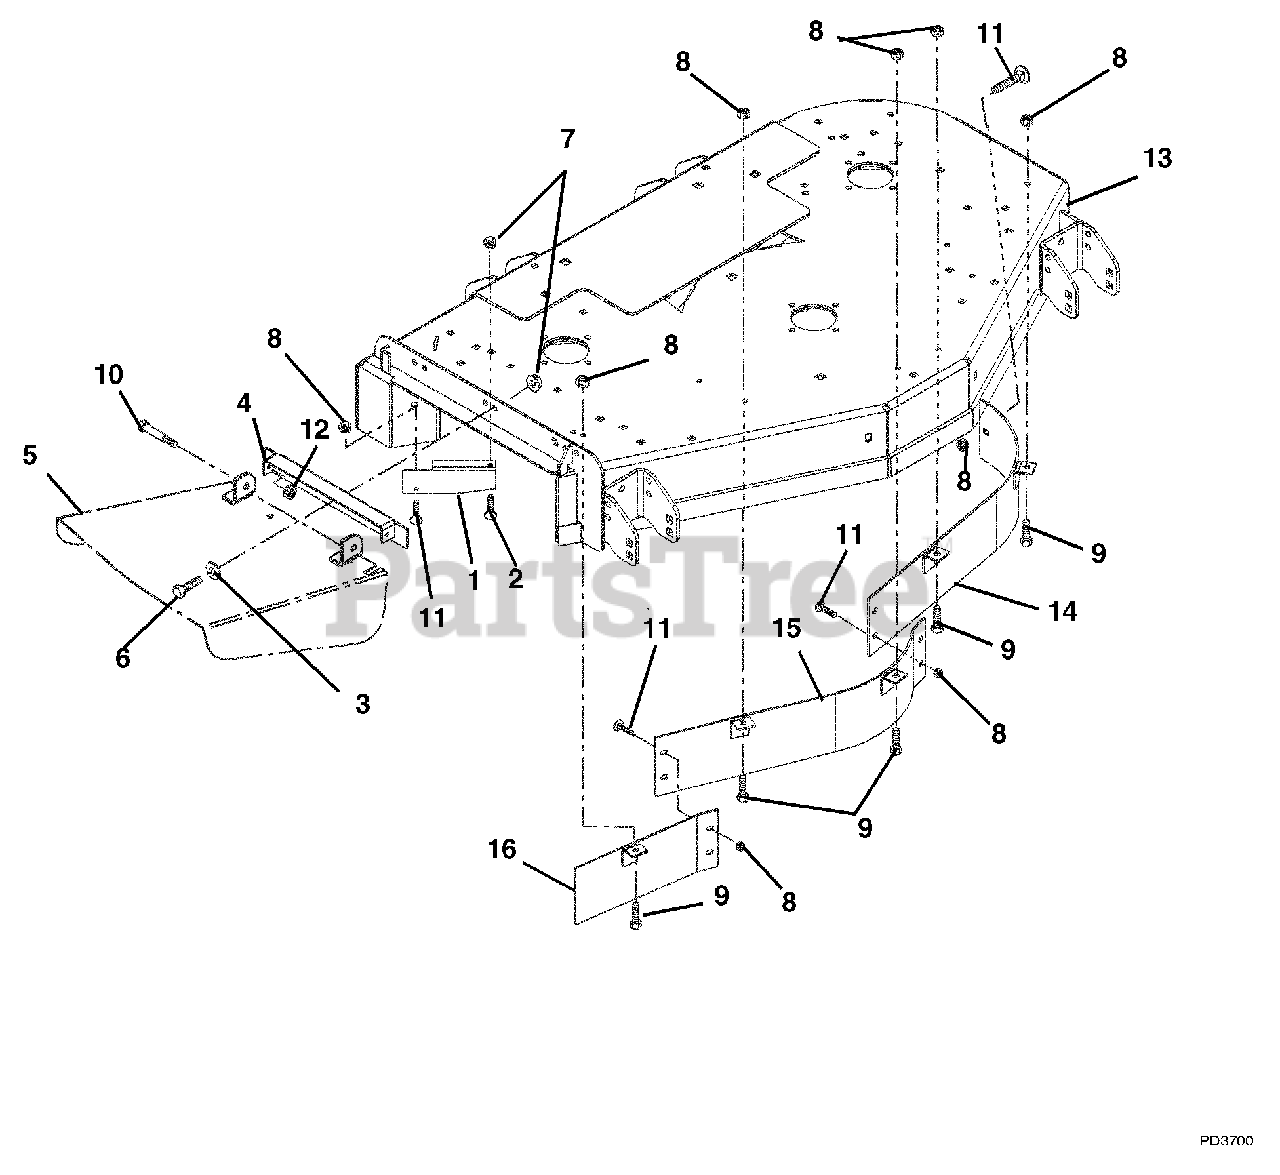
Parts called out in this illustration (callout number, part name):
1	Deflector- 44" (042, 310)
1	Deflector- 48" (043, 311)
1	Deflector- 52" (044, 054)
1	Deflector- 60" (051, 055)
2	Bolt-Round Head Square Neck .38-16 x 1.00 Grade 5
3	Washer-Flat-Steel .38 x .875 x .083 (042, 043, 044, 054, 310, 311)
4	Weldment Discharge Chute Bracket (042, 043, 044, 054, 310, 311)
4	Weldment Discharge Chute Bracket (051, 055)
5	Chute-Discharge (042, 043, 044, 054, 310, 311)
5	Chute-Discharge (051, 055)
6	Bolt-Hex .38-16 x 1.00 Grade 5
7	Nut-Locking-Top-Flange .38-16
8	Nut-Locking-Top-Flange .31-18
9	Bolt-Hex .31-18 x .75 Grade 5
10	Bolt-Shoulder .38-16 x .50 Socket Head
11	Bolt-Round Head Square Neck .31-18 x .75 Grade 5
12	Nut-Locking-Center .38-16
13	Weldment- 44" Mower Deck- Float (042, 310)
13	Weldment- 48" Mower Deck (043, 311)
13	Weldment- 52" Mower Deck (044, 054)
13	Weldment- 60" Mower Deck (051, 055)
14	Weldment- Baffle- Left Front-44" (042, 310)
14	Weldment, Upper Baffle Left 48" (043, 311)
14	Weldment, Upper Baffle Left 52" (044, 054)
14	Weldment, Upper Baffle Left 60" (051, 055)
15	Weldment-Baffle-Center Front - 44" (042, 310)
15	Weldment, Upper Baffle Center 48" (043, 311)
15	Weldment- Baffle-Center Front -52" (044, 054)
15	Weldment- Baffle-Center Front - 60" (051, 055)
16	Weldment-Baffle-Right Front- 44" (042, 310)
16	Weldment, Upper Baffle Right 48" (043, 311)
16	Weldment- Baffle- Right Front - 52" (044, 054)
16	Weldment- Baffle- Right Front - 60" (051, 055)
